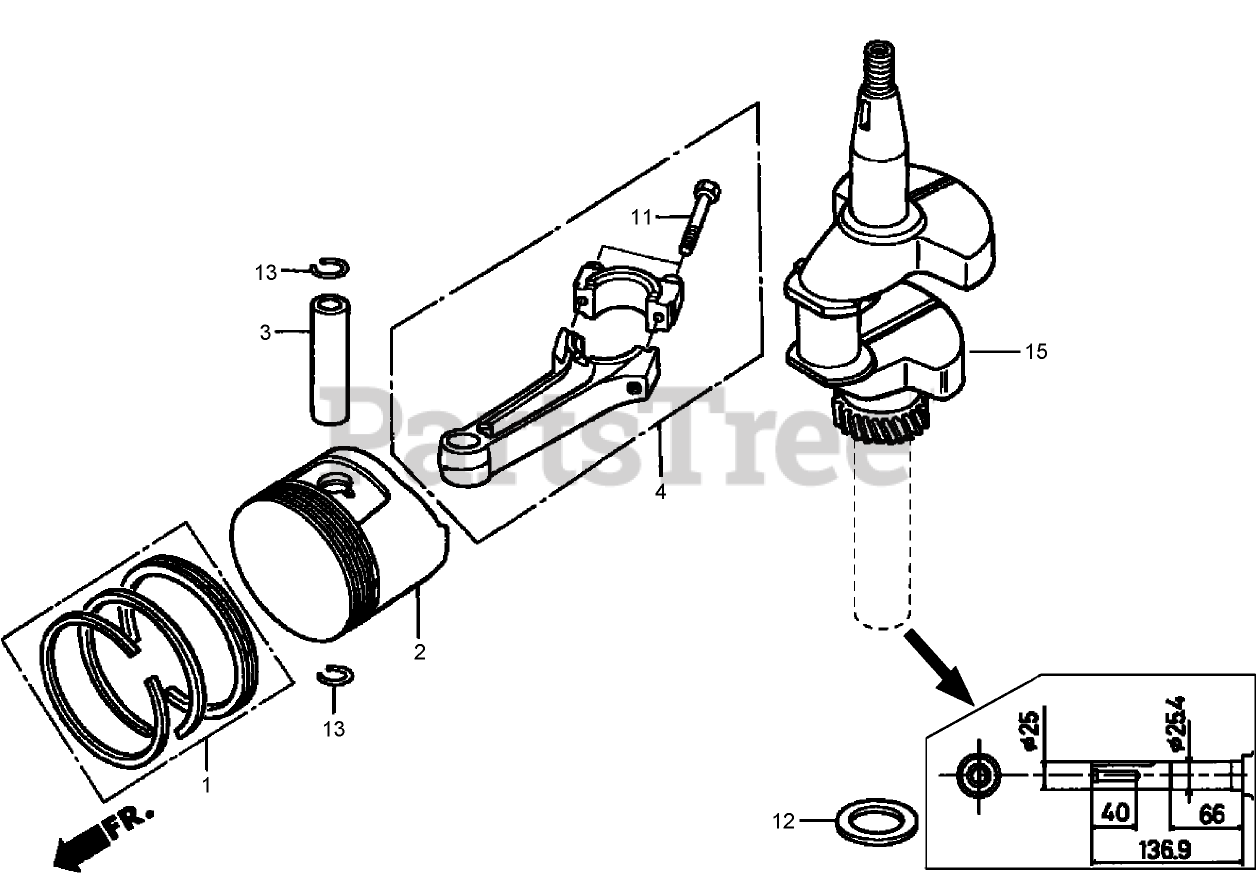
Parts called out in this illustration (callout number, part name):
1	PISTON RING SET (STD) (TEIKOKU)
1	RING SET-PISTON (STD) (NIPPON)
1	PISTON RING SET (O S 0.25) (TEIKOKU)
1	RING SET-PISTON (O S 0.25) (NIPPON)
1	PISTON RING SET (O S 0.50) (TEIKOKU)
1	RING SET-PISTON (O S 0.50) (NIPPON)
1	PISTON RING SET (O S 0.75) (TEIKOKU)
1	RING SET-PISTON (0.75) (NIPPON)
2	PISTON (STD)
2	PISTON (O S 0.25)
2	PISTON (O S 0.50)
2	PISTON (0.75)
3	Pin-Piston
4	CONNECTING ROD ASM
4	CONNECTING ROD ASM (US 0.25)
11	BOLT-ROD, CONNECTING
12	WASHER-THRUST (25.6 mm)
13	CLIP-PIN, PISTON (18 mm)
15	CRANKSHAFT
